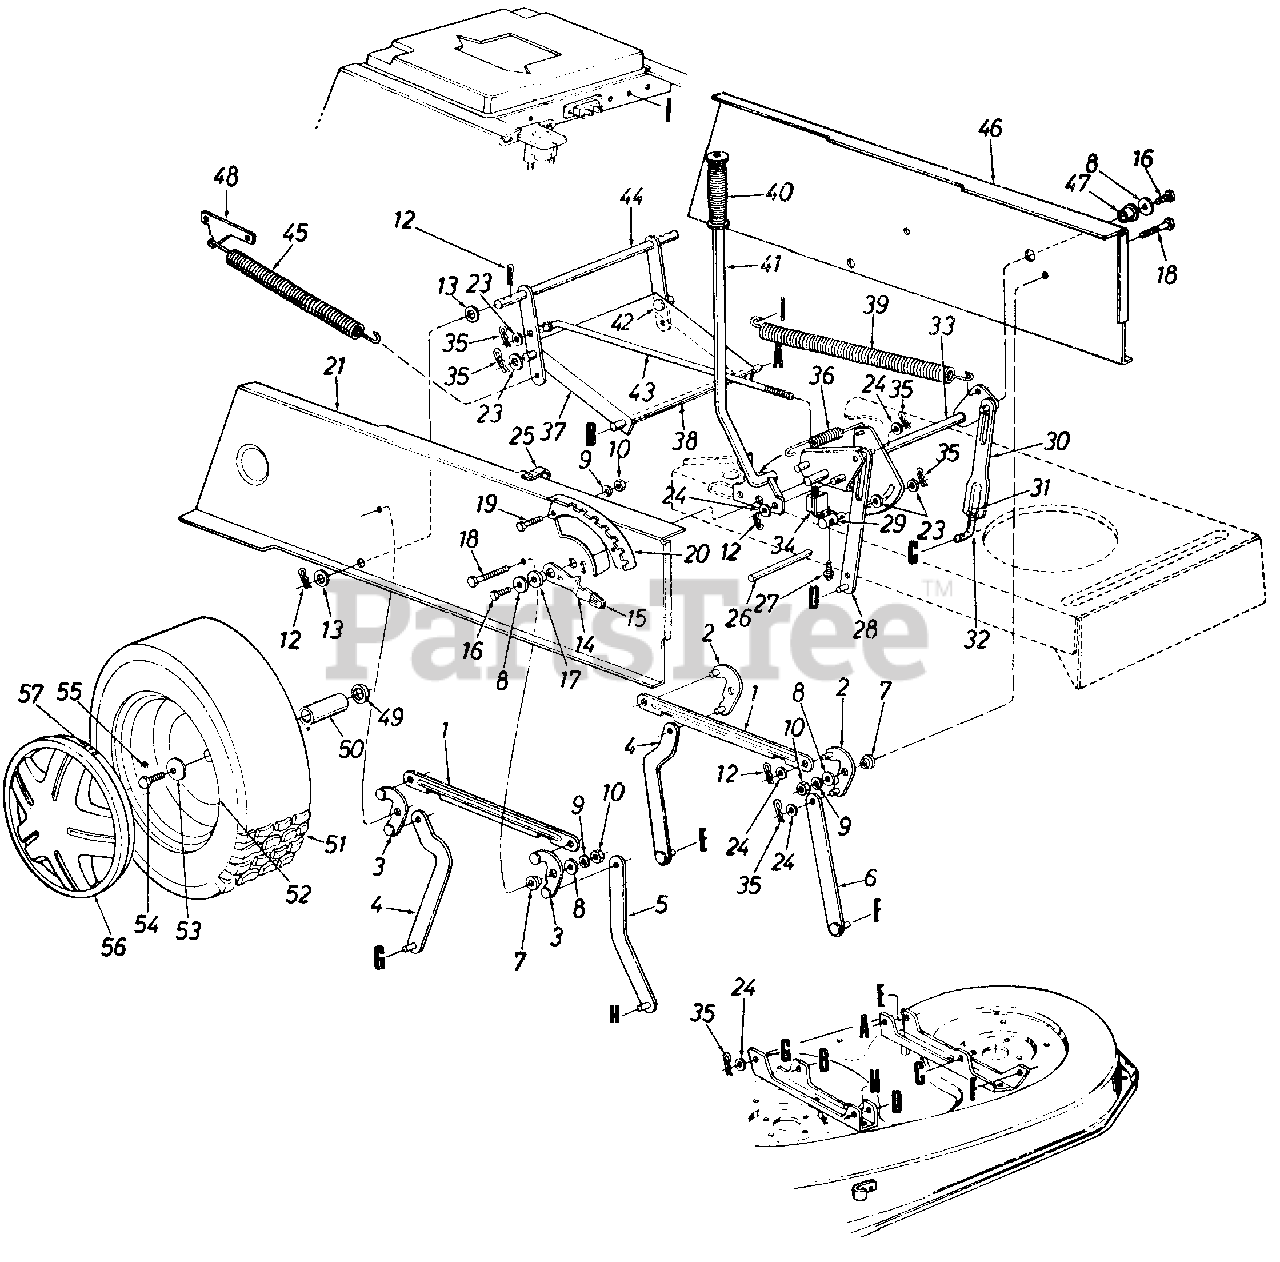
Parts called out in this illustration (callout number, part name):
1	Connecting Rod
2	Pivot Link Ass'y.-L.H.
3	Pivot Link Ass'y.-R.H.
7	Shld. Spacer .318" I.D.
8	Fl-Wash .344" I.D. x 1.125"
9	L-Wash. 5/16" I.D.
10	Hex Nut 5/16-18 Thd.
12	Cotter Pin 1/8" Dia.
13	Fl-Wash. .635" I.D. x 1.0" O.D.
14	Deck Lift-Down Stop
16	Hex Wash. TT-Tap Scr. 5/16-18 x .75" Lg.
17	Flange Brg. .63" I.D.
18	Hex Wash. TT-Tap Scr. 5/16-18 x.875" Lg.
19	Hex Bolt 5/16-18 x .75" Lg.
20	Index Brkt.
21	Upper Frame-R.H.
23	Fl-Wash. .385" I.D. x .87" O.D.
24	Fl-Wash. .531" I.D. x .93" O.D.
26	Running Board Rod
27	Truss Mach. Scr. #10 x .5" Lg.
31	Hex Nut 1/2-20 Thd. (Gr. 5)
32	Lift Link Adjuster
33	Lift Shaft Ass'y.
34	Safety Switch
35	Inter. Cotter Pin 318" Dia.
36	Extension Spring
37	Stabilizer Bracket
38	Shaft 1/2" Dia. x 10.28" Lg.
39	Extension Spring
40	Grip
41	Deck Lift Handle Ass'y.
42	Weld Pin .375" Dia. x 1.25" Lg.
43	Disengagement Rod
44	Stabilizer Shaft Ass'y.
45	Extension Spring
46	Upper Frame-L.H.
47	Flange Brg. .632" l.D.
48	Deck Spring Brkt.
49	Fl-Wash. .76" I.D. x 1.49" O.D.
50	Sleeve .75" l.D. x 1.0" O.D.
52	Wheel Rim Only
53	Bell-Wash. .345" I.D. x .88' O.D.
54	Hex L-Bolt 5/16-24 x .75" Lg.
55	Air Valve
56	Hub Cap
57	Spring Clip
